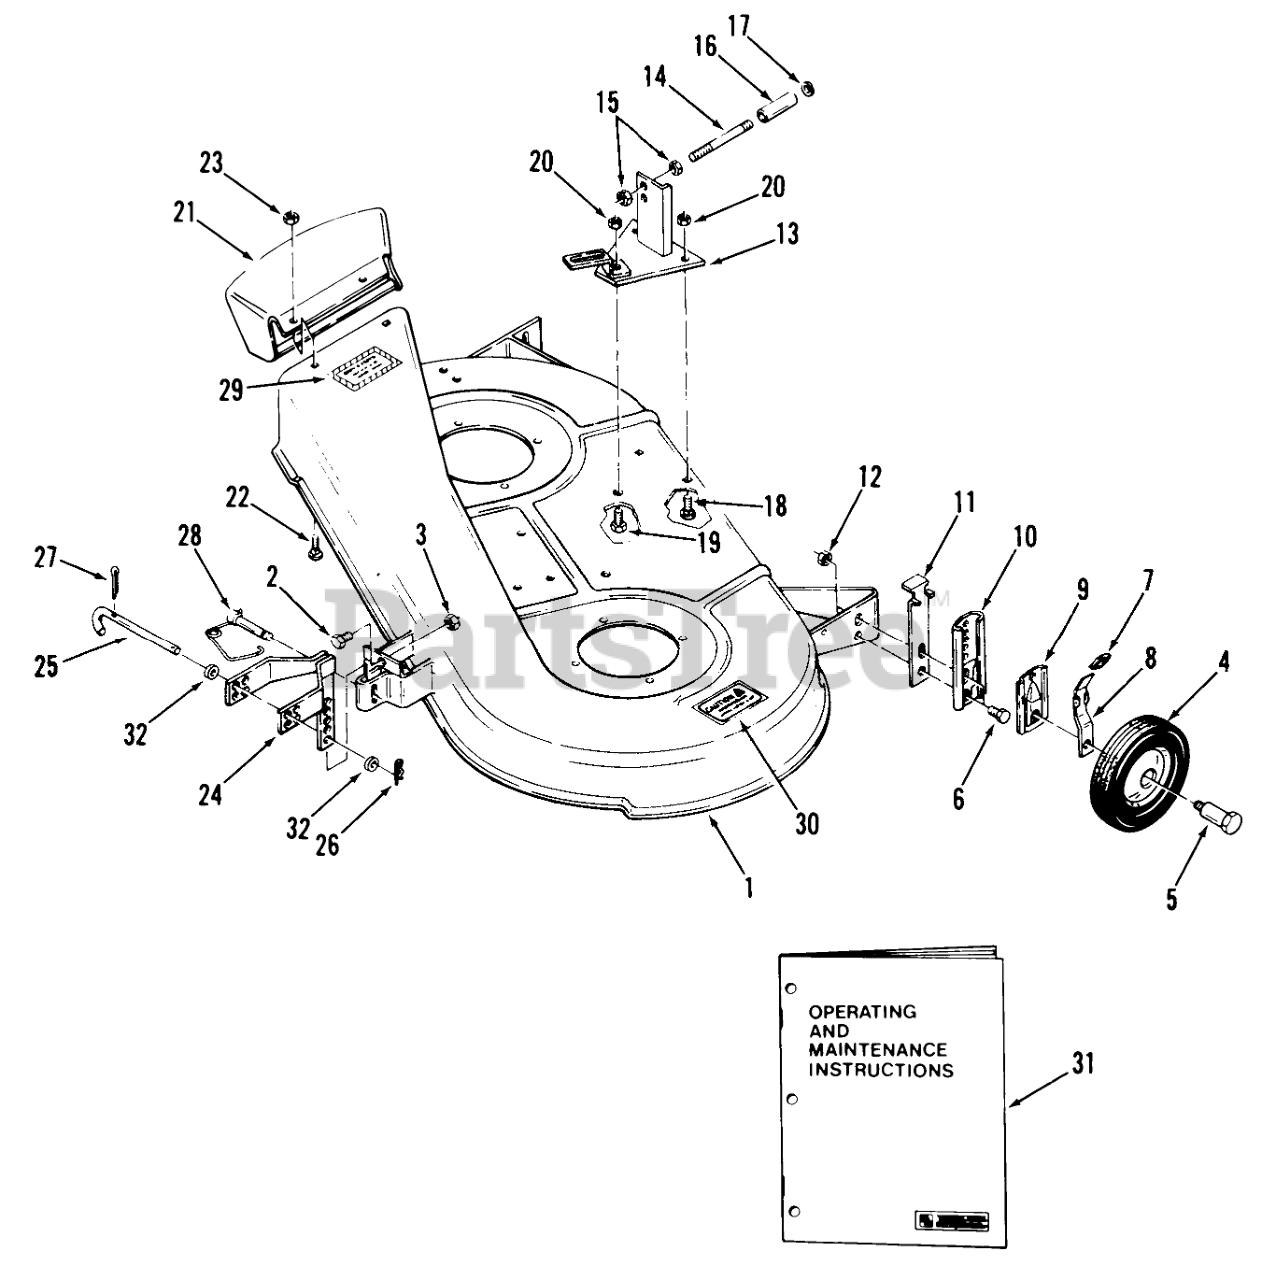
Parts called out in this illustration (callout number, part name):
1	Mower Deck for 05-32MS01
1	Mower Deck for 05-32XS01,02
2	BOLT
3	Nut
4	Wheel 6 X 1.25
5	BOLT-SHOULDER
6	Bolt-Special
7	HT ADJ TIP RED VINYL
8	HT ADJ SPRING LEVER
9	HT ADJ SLIDE
10	HT ADJ BACK PLATE
11	SAFETY-STOP& LIFT
12	Nut
13	Rear Hanger Support
14	ROD-HANGER
15	Eslok Nut
16	SPACER
17	Snap Ring
18	Bolt-Carriage
19	BOLT
20	Nut
21	ASSY-CHUTE EXT R
22	CARRIAGE BOLT -4
23	Nut
24	Front Hanger
25	"J" Pin
26	Hairpin Cotter
28	PIN-LOCKING
29	DECAL
30	Caution Decal
31	Operating and Maint. Inst. for 05-32XS01,32MS01
31	Owner-s Manual (Mower)
32	WASHER
